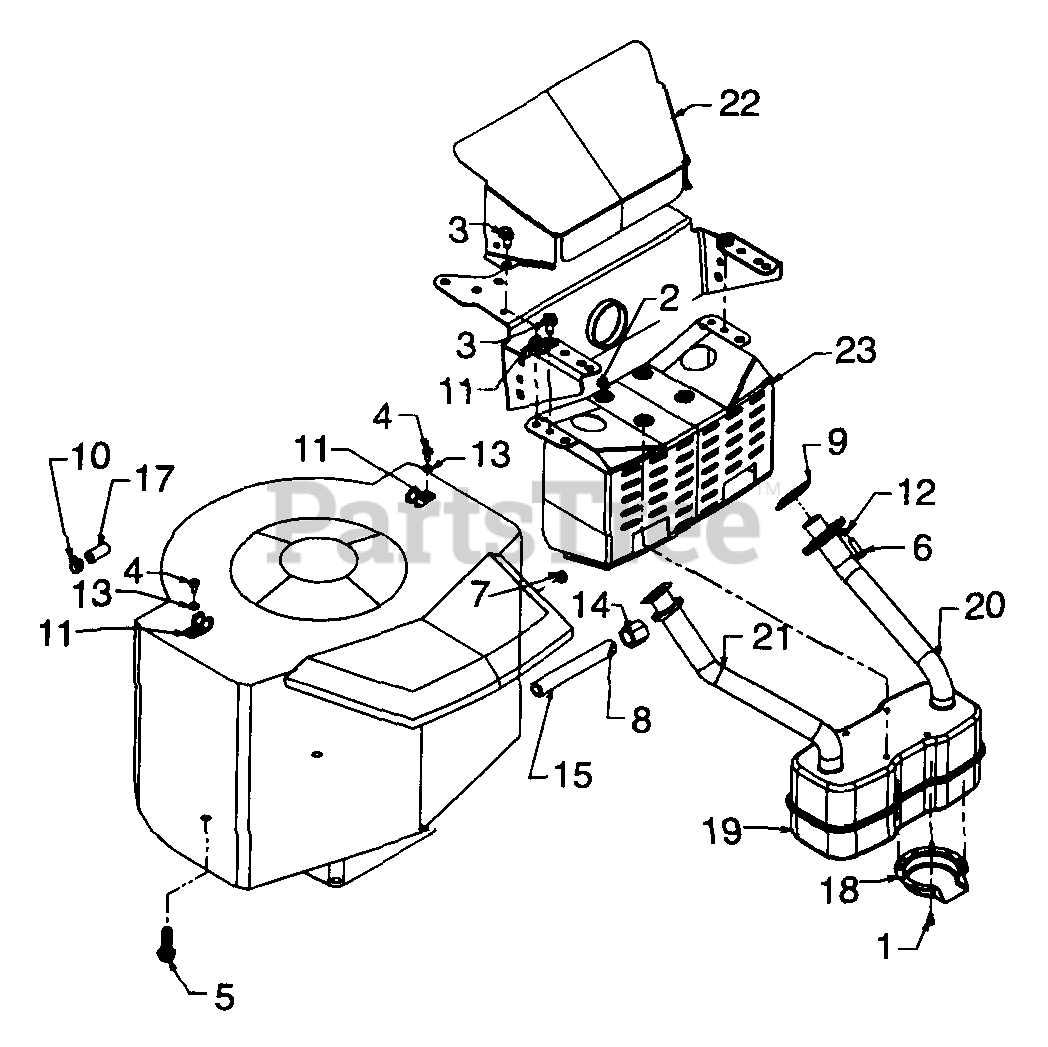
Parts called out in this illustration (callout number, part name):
1	Hex Tap Scr. #8-32 x .38" Lg.
2	Hex Wash. TT-Tap Scr. 1/4-20 x 5" Lg.
3	Hex Wash. TT-Tap Scr. 5/16-18 x .62"
4	Truss Mach. Scr. #10 x .5" Lg.
5	Hex Hd. Tap Scr. 3/8-16 x 1.25" Lg.
6	Hex Bolt 1/4-20 x .75"Lg.
7	Hex Sems Nut 1/4-20 Thd.
9	Exhaust Gasket
10	Hose Clamp
11	Clamp
12	L-Wash. 1/4" I.D.
13	Fl-Wash. .188" I.D. x .438" O.D.
14	Oil Drain Cap
15	Pipe Nipple 3/8 x 18 NPT.
17	Fuel Line 26" Lg.
18	Deflector: Muffler
19	Muffler
20	Exhaust Pipe - L.H.
21	Exhaust Pipe - R.H.
